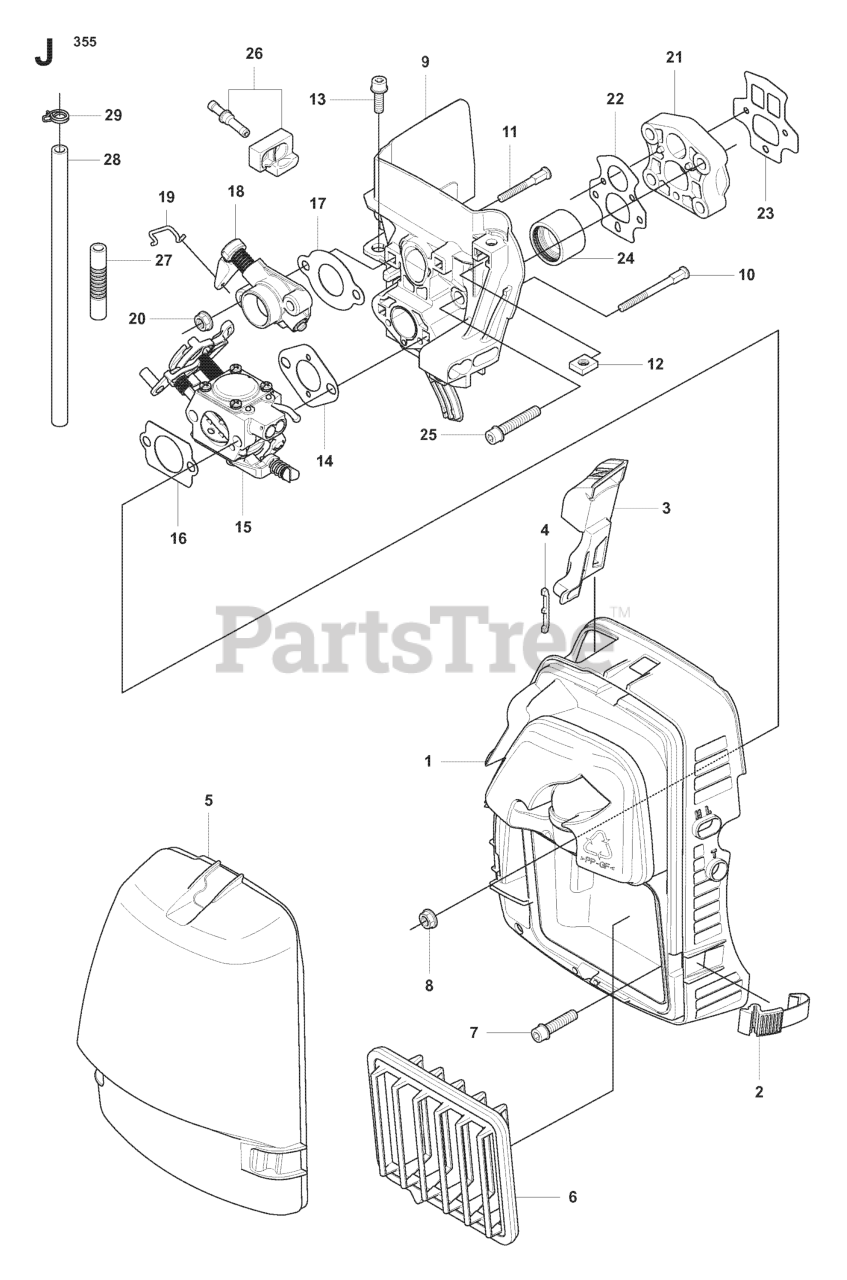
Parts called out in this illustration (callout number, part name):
1	FILTER HOLDER
3	CHOKE CONTROL
5	FILTER COVER
6	FILTER
9	INSULATION WALL
14	%GASKET
15	CARBURETOR WT-814A
18	VALVE HOUSING
24	INLET PIPE
25	SCREW IHSCFM
27	SUCTION HOSE
28	RP FUEL HOSE
29	HOSE CLAMP
